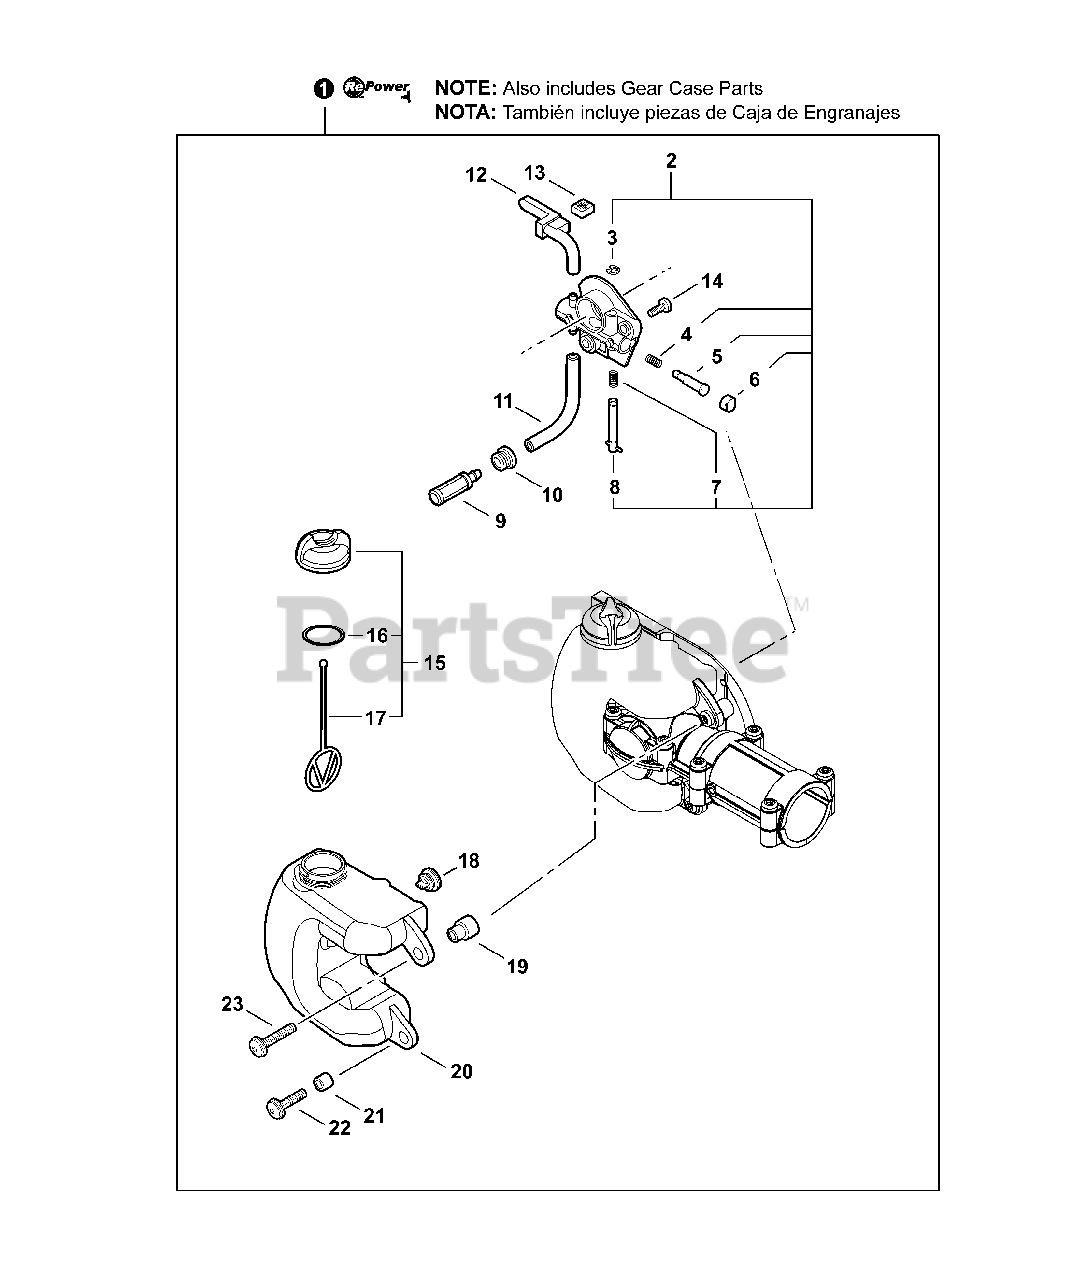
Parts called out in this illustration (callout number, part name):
1	GEAR CASE ASSY
2	AUTO-OILER ASSY
5	PLUNGER ASSY
6	CAP, PLUNGER
8	ADJUSTER, OILER
9	FILTER, OIL
10	GROMMET
11	PIPE, IMPULSE 3×6×75
12	PIPE, OIL OUTLET
13	PAD, FOAM
14	SCREW 5×10
15	CAP ASSY
16	O-RING 18
17	CONNECTOR, CAP L= 60 MM
18	VENT ASSY
19	COLLAR 6
20	TANK, OIL
21	SPACER 6.2×7.8×6
22	BOLT 5×20
23	SCREW M5×25
